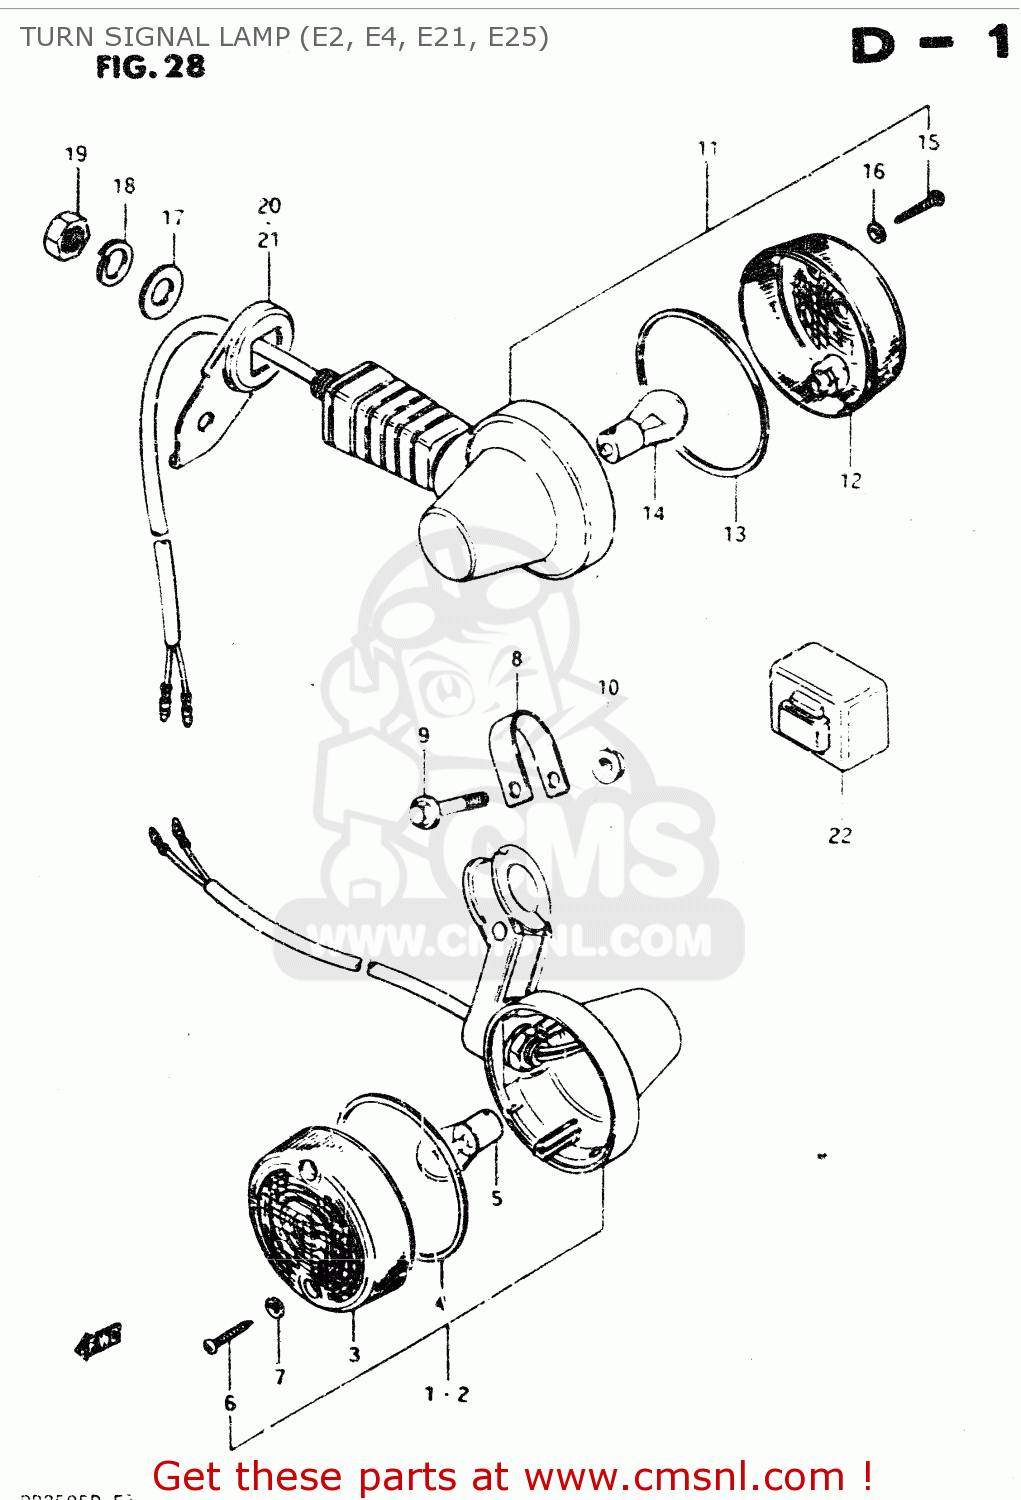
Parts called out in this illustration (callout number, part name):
1	LAMP, FRONT TURN SIGNAL RH
2	LAMP, FRONT TURN SIGNAL LH
3	LENS
4	GASKET (NAS)
5	BULB 12V 21W
6	SCREW TAPP.
7	GASKET (NAS)
8	PLATE
9	BOLT 5X42
10	NUT
11	LAMP ASSEMBLY,REAR TURN SIGNAL
12	LENS
13	GASKET (NAS)
14	BULB 12V 21W
15	SCREW TAPP.
16	GASKET (NAS)
17	WASHER
18	WASHER,LOCK 12
19	NUT
20	BRACKET,REAR TURN SIGNAL LAMP
21	BRACKET,RR TURNSIGNAL LAMP,L
22	RELAY,TURN SIGNAL
